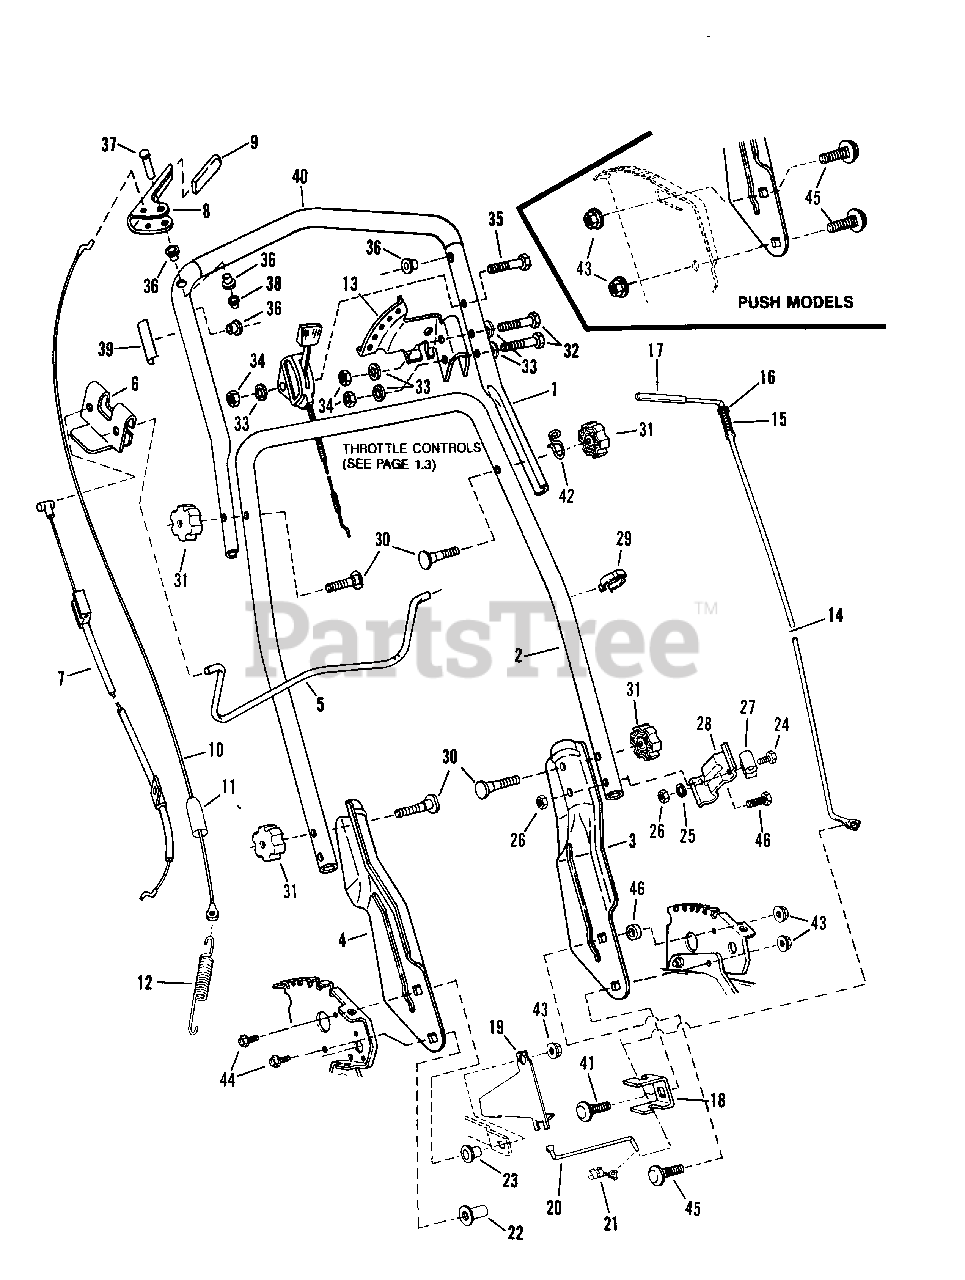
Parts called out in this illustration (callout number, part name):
1	HANDLE, Upper
2	HANDLE, Middle
3	HANDLE, Lower Left Hand
4	HANDLE, Lower Right Hand
5	CONTROL, Blade
6	CLIP, Blade Control
7	CABLE, Blade Control
8	HANDLE, Wheel Drive
9	GRIP, Wheel Drive Handle
10	CABLE, Clutch Pull(Z-Bend)
11	COVER, Vinyl
12	SPRING, Clutch
13	SECTOR, Speed
14	LEVER, Speed Control
15	SPRING, Speed Control
16	WASHER, 3/8" Flat
17	GRIP, Speed Control Handle
18	ANCHOR, Speed Control
19	GUIDE, Lower V-Belt
20	ROD, Transfer
21	CLIP, Transfer Rod
22	TEE - NUT, 5/16-18
23	BUSHING, Differential
24	SCREW, 1/4-28 x 1-38" Hex Cap
25	WASHER,1/4 Internal lock
26	NUT, 1/4-28 Hex
27	GUIDE, Rope
28	BRACKET, Rope Guide
29	CLIP, Wiring Harness
30	SCREW, 1/4-20 x 1-7/8" Curved Head
31	KNOB, 5/16-18
32	SCREW, 1/4-28 x 1-3/8" Hex Cap
33	WASHER, 1/4 Internal Tooth Lock
34	NUT, 1/4-20 Hex
35	SCREW, 1/4-28 x 1-3/4" Hex Cap
36	BUSHING
37	PIN, Clutch Handle .250 x 1.50
38	NUT, Push (for handle pin)
39	DECAL, Blade Control
40	GRIP, Foam
41	BOLT, 5/16-18 x 5/8" Carriage
42	RETAINER, Rope
43	NUT, 5/16-18 Hex Flange Lock
44	BOLT, 5/16-18 x 1" Hex Flange Lock
45	BOLT, 5/16-18 x 1" Carriage
46	SCREW, 1/4-28 x 1-3/4" Hex Cap
